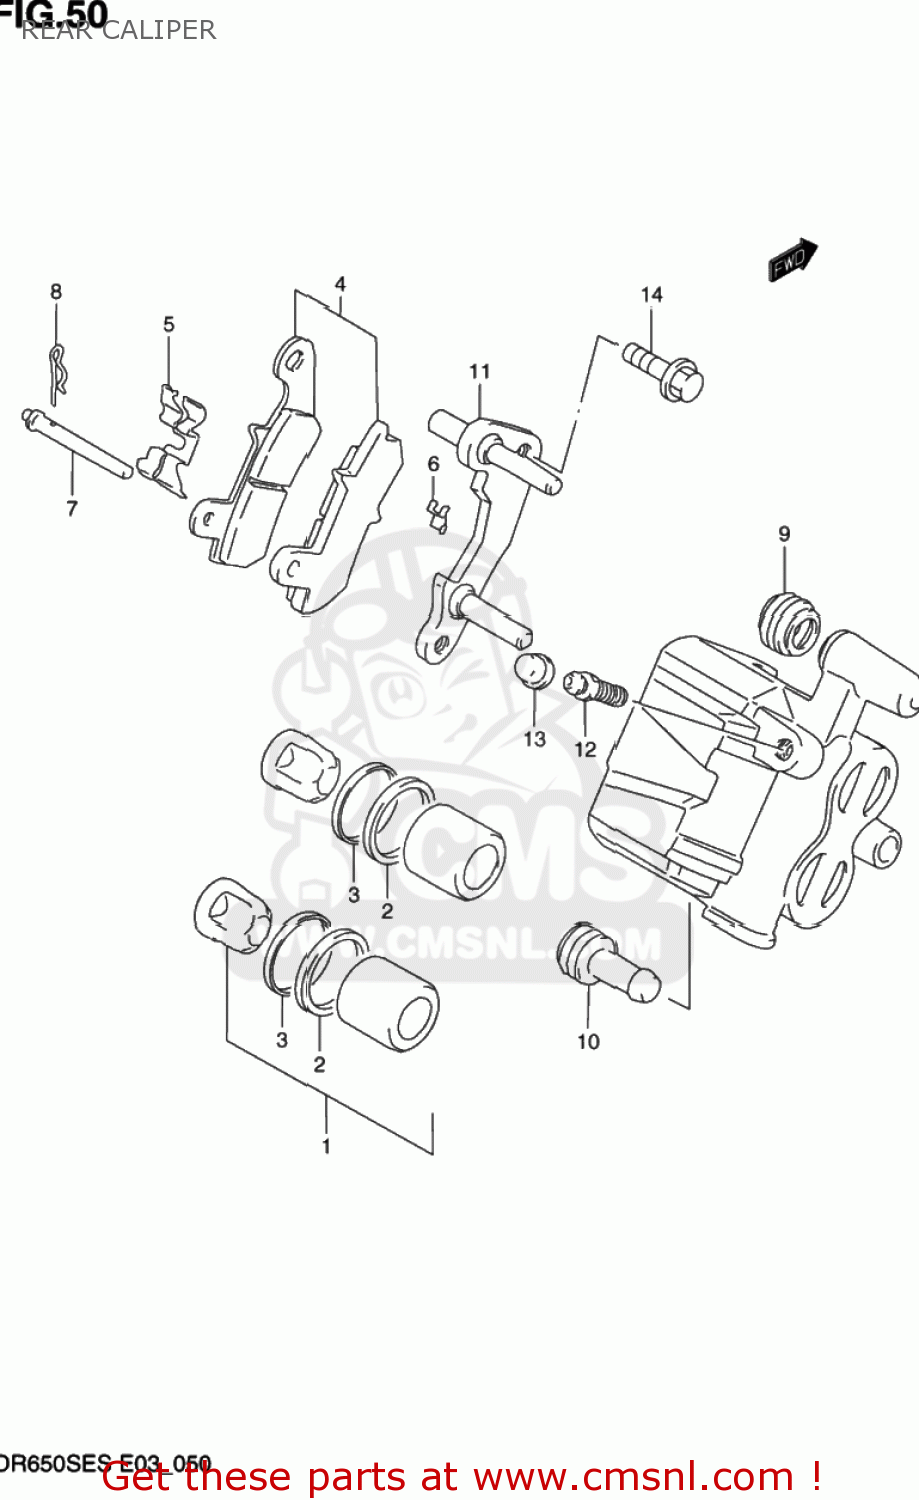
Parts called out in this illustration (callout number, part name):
1	BRAKE PISTON SET
2	SEAL,PISTON
3	SEAL,WIPER
4	PAD SET (NAS)
5	SPRING,PAD
6	GUIDE,PAD
7	PIN,PAD
8	CLIP,PAD PIN
9	BOOT,AXLE
10	INSULATOR,AXLE
11	CARRIER
12	BLEEDER
13	CAP,BREATHER
14	BOLT(8X22)
